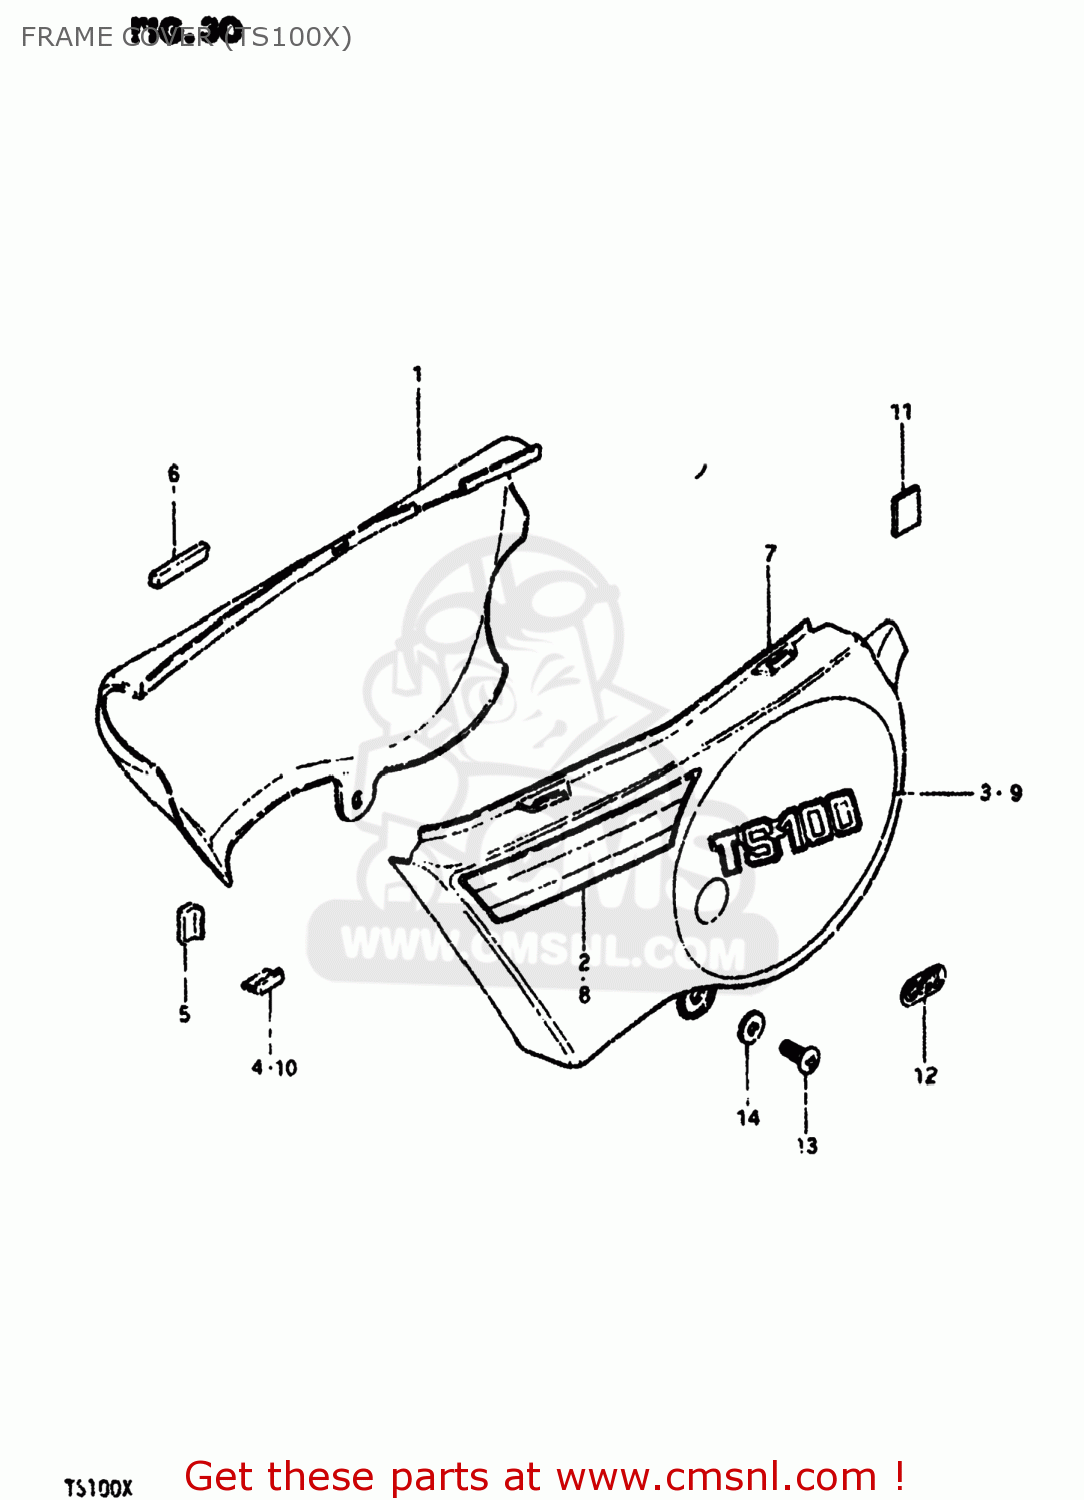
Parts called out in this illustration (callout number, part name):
1	COVER,FRAME,RIGHT
2	TAPE,FRAME COVER
3	EMBLEM
4	CUSHION,FRAME COVER
5	CUSHION,FRAME COVER
6	CUSHION,FRAME COVER
7	COVER,FRAME,LEFT
8	TAPE,FRAME COVER,LEFT
9	EMBLEM,FRAME COVER
10	CUSHION,FRAME COVER
11	PROTECTOR(170X95X3.0)
12	EMBLEM,CCIS
13	SCREW 6X12
14	WASHER
